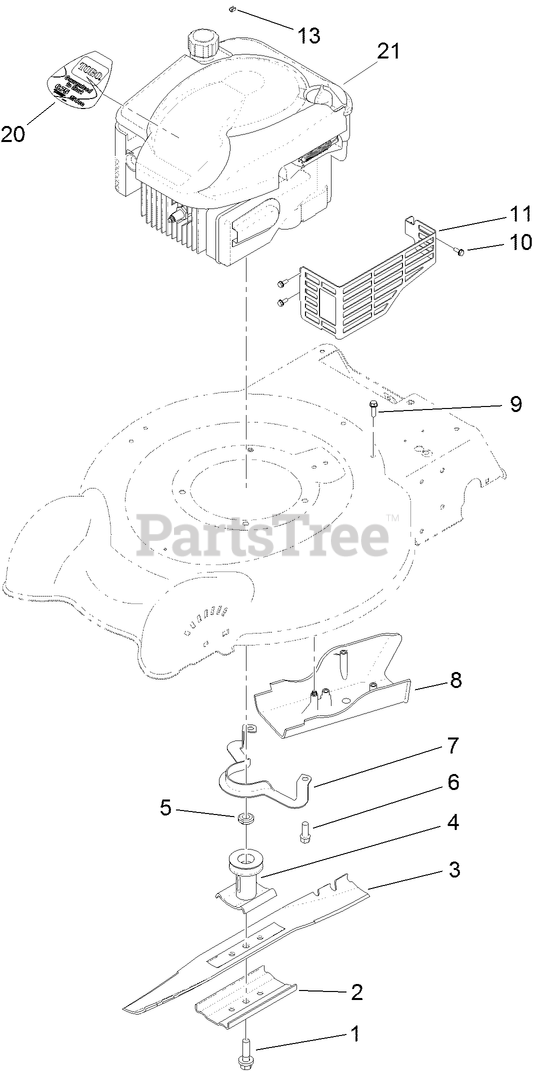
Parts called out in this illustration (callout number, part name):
1	BOLT-BLADE
2	SUPPORT-BLADE
3	BLADE-20 INCH
4	DRIVER-BLADE
5	Spacer-Driver
6	SCREW-TAPTITE
7	Guide-Belt
8	COVER-BELT
9	SCREW-HWH
10	SCREW-TAPTITE
11	SHIELD-MUFFLER
13	STOP-ROPE
